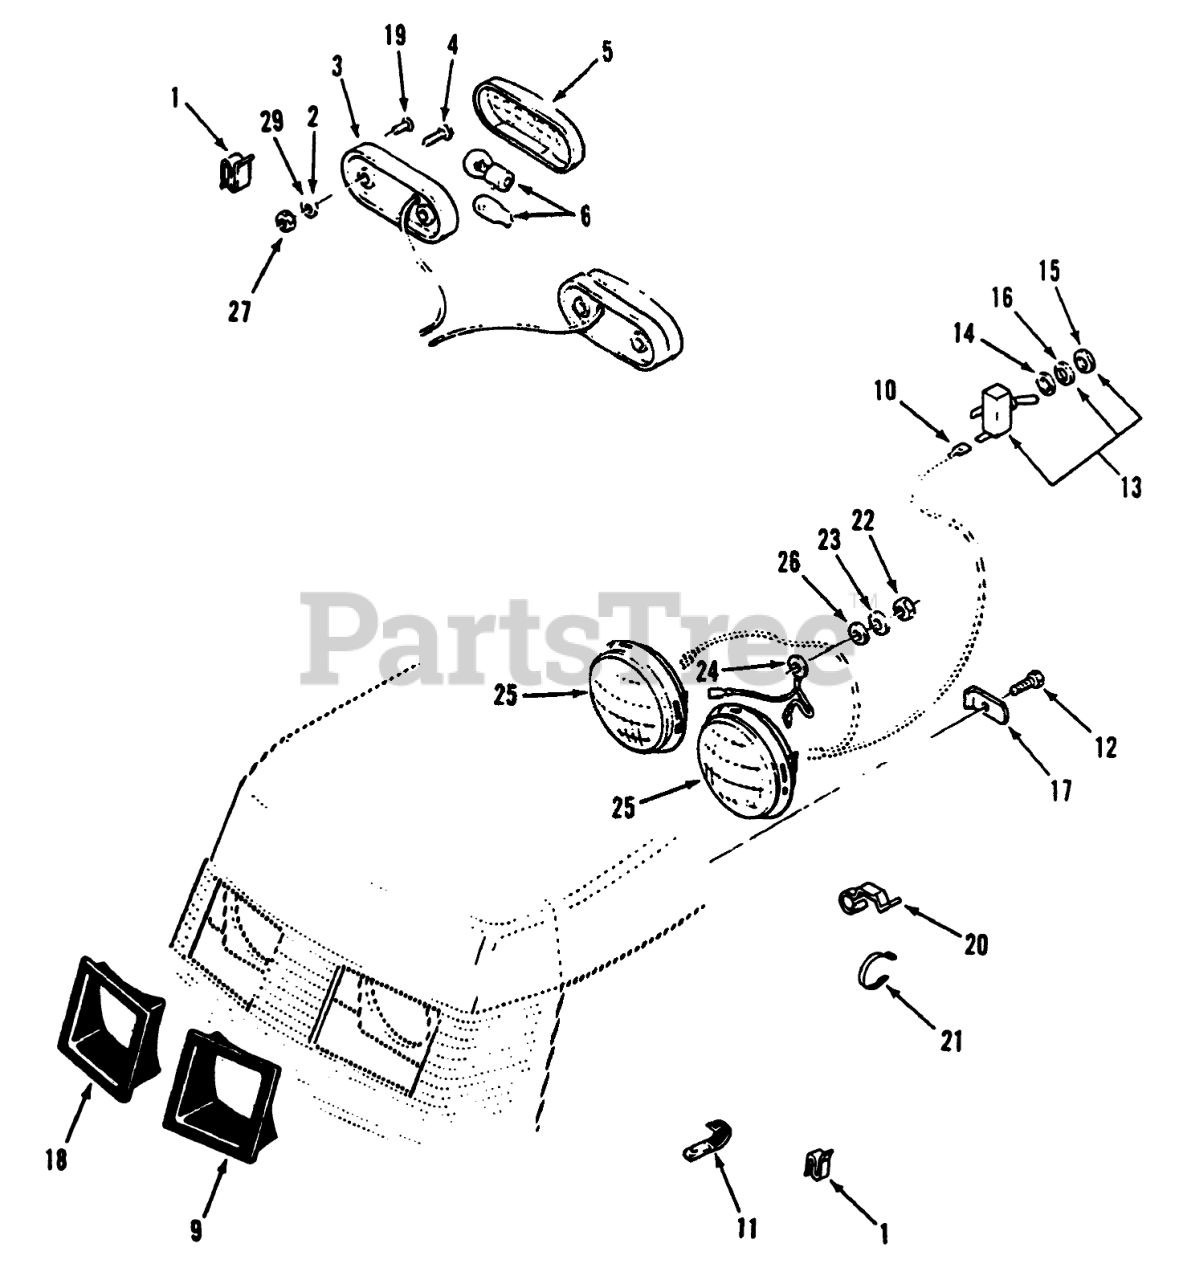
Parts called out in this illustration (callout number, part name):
1	SPEED CLIP
2	WASHER-LOCK
3	BASE-TAIL LIGHT
4	Screw
5	LENS-TAIL LIGHT
6	Bulb
9	BEZEL-HEADLIGHT, LH
10	Terminal
11	CLIP
12	Bolt
13	SWITCH-LIGHTS
14	Washer
16	TAB-WASHER
17	LOCK-HEADLIGHT
18	BEZEL-HEADLIGHT, RH
19	RIVET-POP
20	CLIP-WIRE
21	PLASTIC TIE
22	NUT-LOCK, NI
23	WASHER-LOCK, INTERNAL
24	LIGHT GROUND WIRE
25	HEADLAMP
26	WASHER-PLAIN
27	Nut
